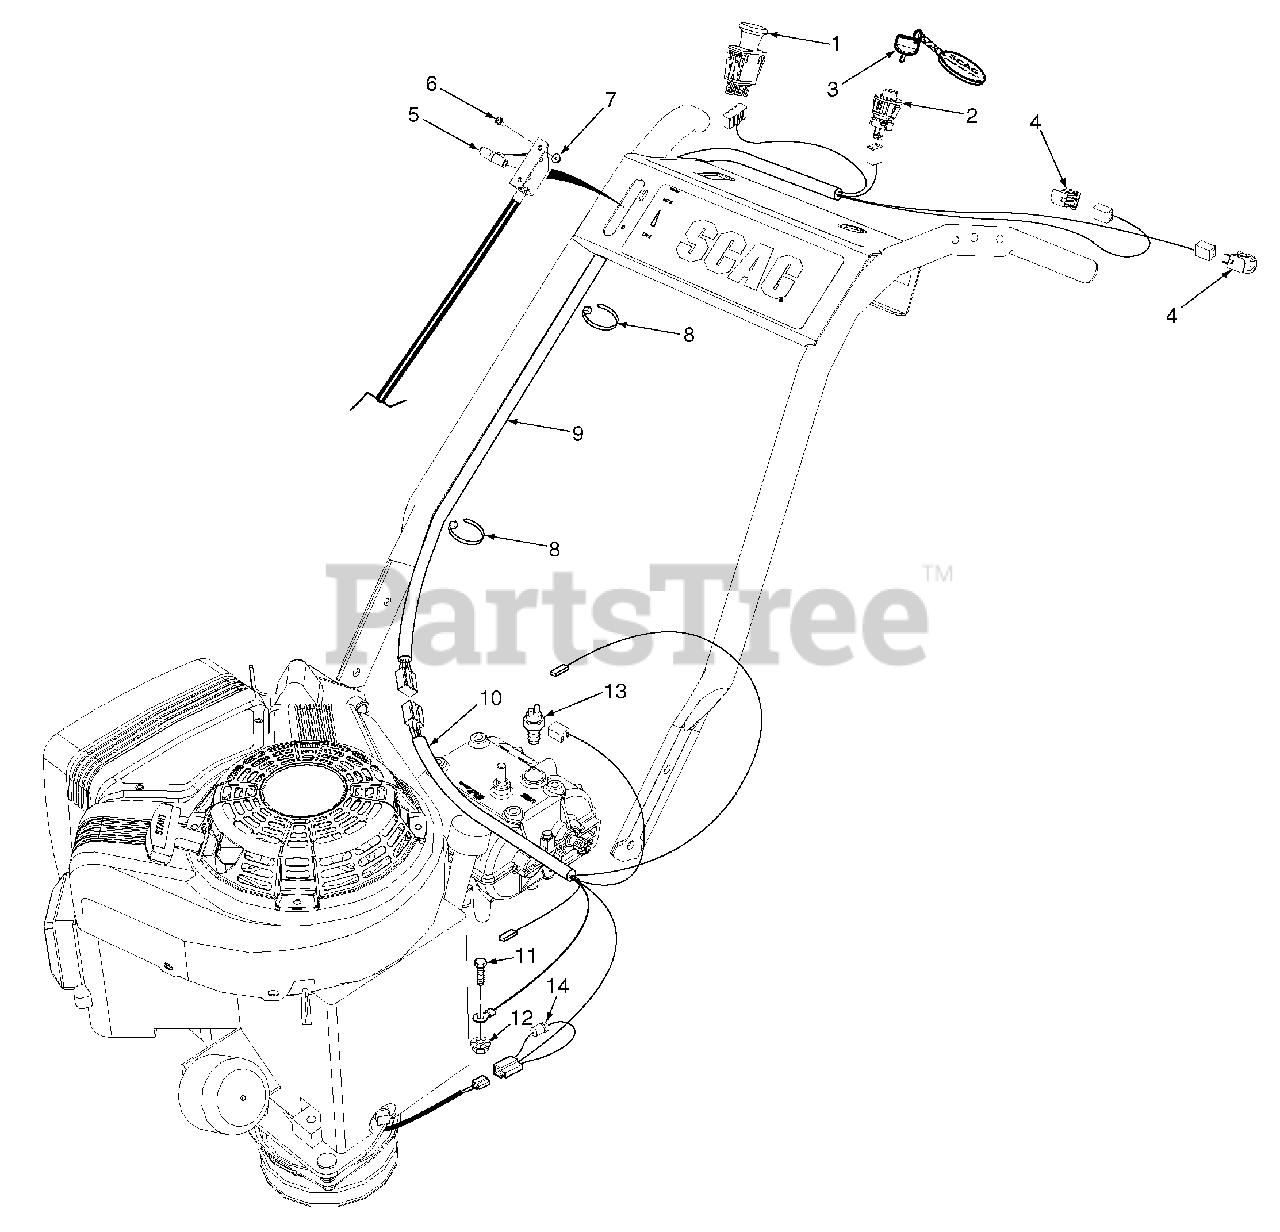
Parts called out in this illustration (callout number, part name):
1	Switch, PTO 10 Amp
2	Keyswitch
3	Key Chain w/Keys
4	Switch
5	Throttle Cable
6	Screw, #10-32 x 1/2"
7	Nut, #10-32
8	Cable Tie
9	Wire Harness, Handle Bar
10	Wire Harness, Engine Deck
11	Bolt, Serrated Flange 5/16-18 x 1-1/2"
12	Nut, Serrated Flange 5/16-18
